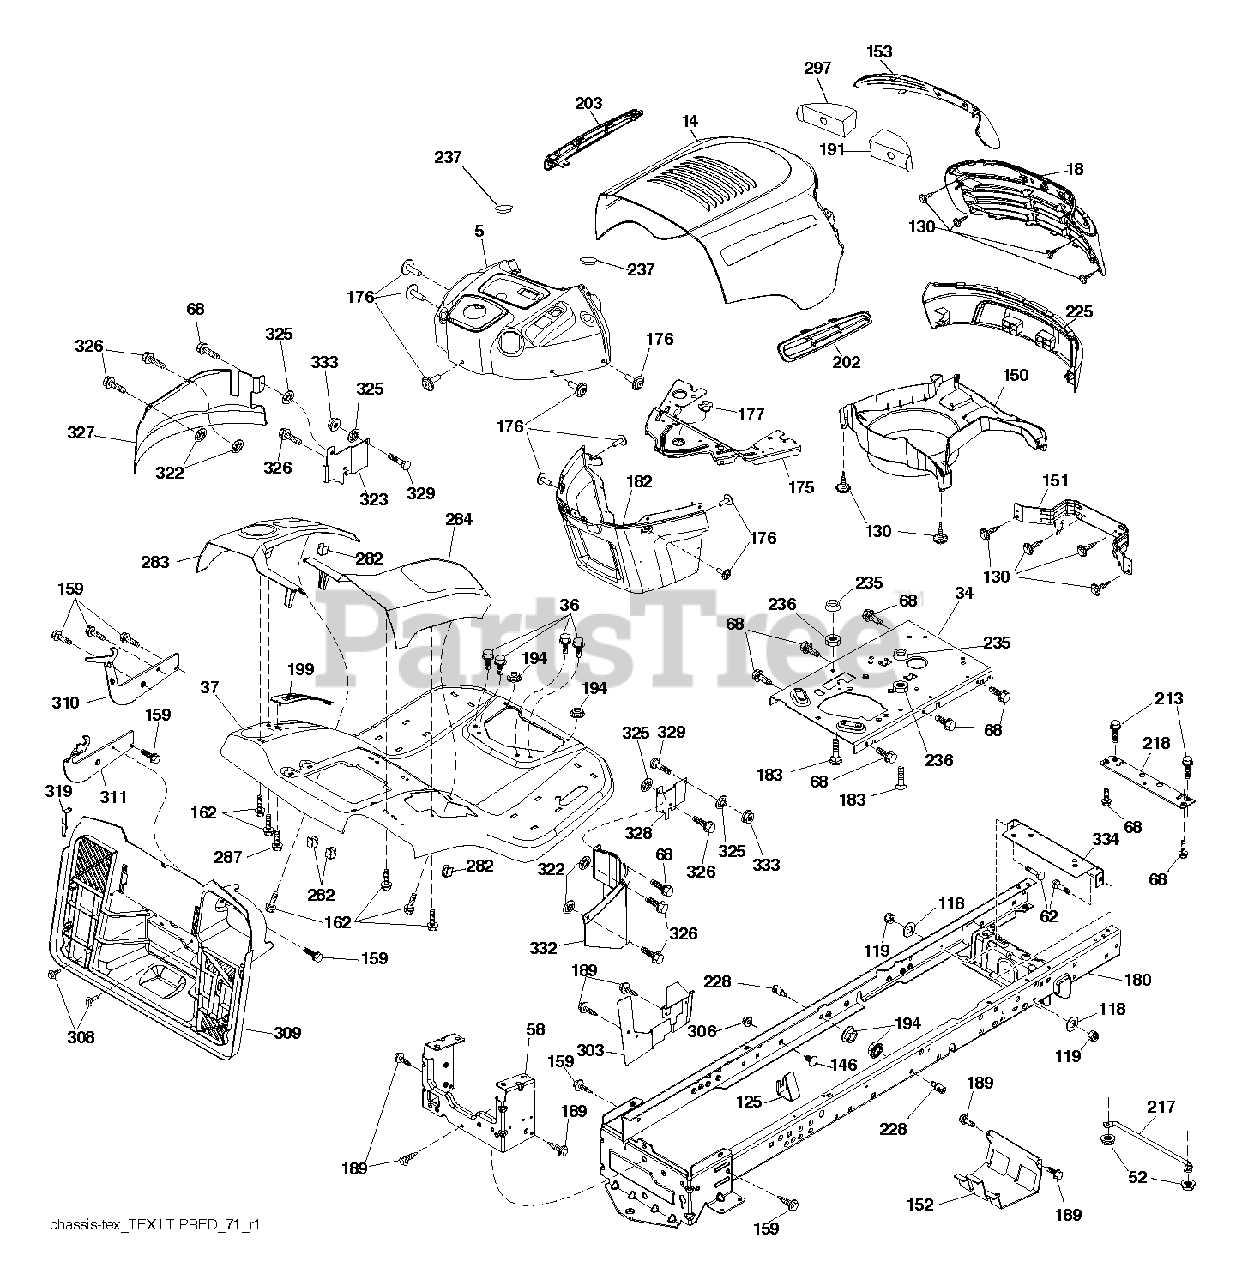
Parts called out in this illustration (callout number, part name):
36	SCREW 5/16"
52	LOCKNUT
58	DRAWBAR UPPER 2PC SMALL FENDER
68	SCREW LT
119	LOCKNUT
125	Fuel Line Clip
130	SCREW.#10 X 0.750.BOS THREAD
146	BOLT.RDHD.SHT.SQNK.3
151	BRACKET.PIVOT.ALPHA.LT
152	SHIELD BROWNING
153	LENS.PREDATOR.LT
159	SCREW, 3/8-16X3/4
162	SCREW.HI-LO.CONSOLE
175	CROSSMEMBER
176	SCREW.#10-24X5/8.RN.QU
177	BUSHING STEERING
182	DASH.LWER.PREDATOR/HUSQ.LT
183	BOLT.5/16-18X1-1/4 FULL THD
189	SCREW
191	INSERT.REFLECT.PREDATOR.LT.RH
194	NUT LOCK HEX FLANGE 5/16-18
213	BOLT
217	ROD.PIVOT.HOOD
218	X-PIECE.HOOD.STOP.NON/
228	STUD.FASTNER.W/ANTI-ROTATE
235	SPACER FENDER
236	NUT.CENTERLOCK.5/16-
237	PLUG.MOUNT.CARGO.BLK
282	CLIP.RETAINER.CONSOLE.LT.HUSQ
297	REFLECTOR.INSERT.PRED.LH.LT
306	NUT LOCK FLG 3/8-16 UNC
308	BOLT, 5/16-18 X 1 3/4
322	PALNUT 1/4
326	SCREW 14-20 X 5/8
329	BOLT
333	NUT.71038.31-18.HEX.NYLOCK
